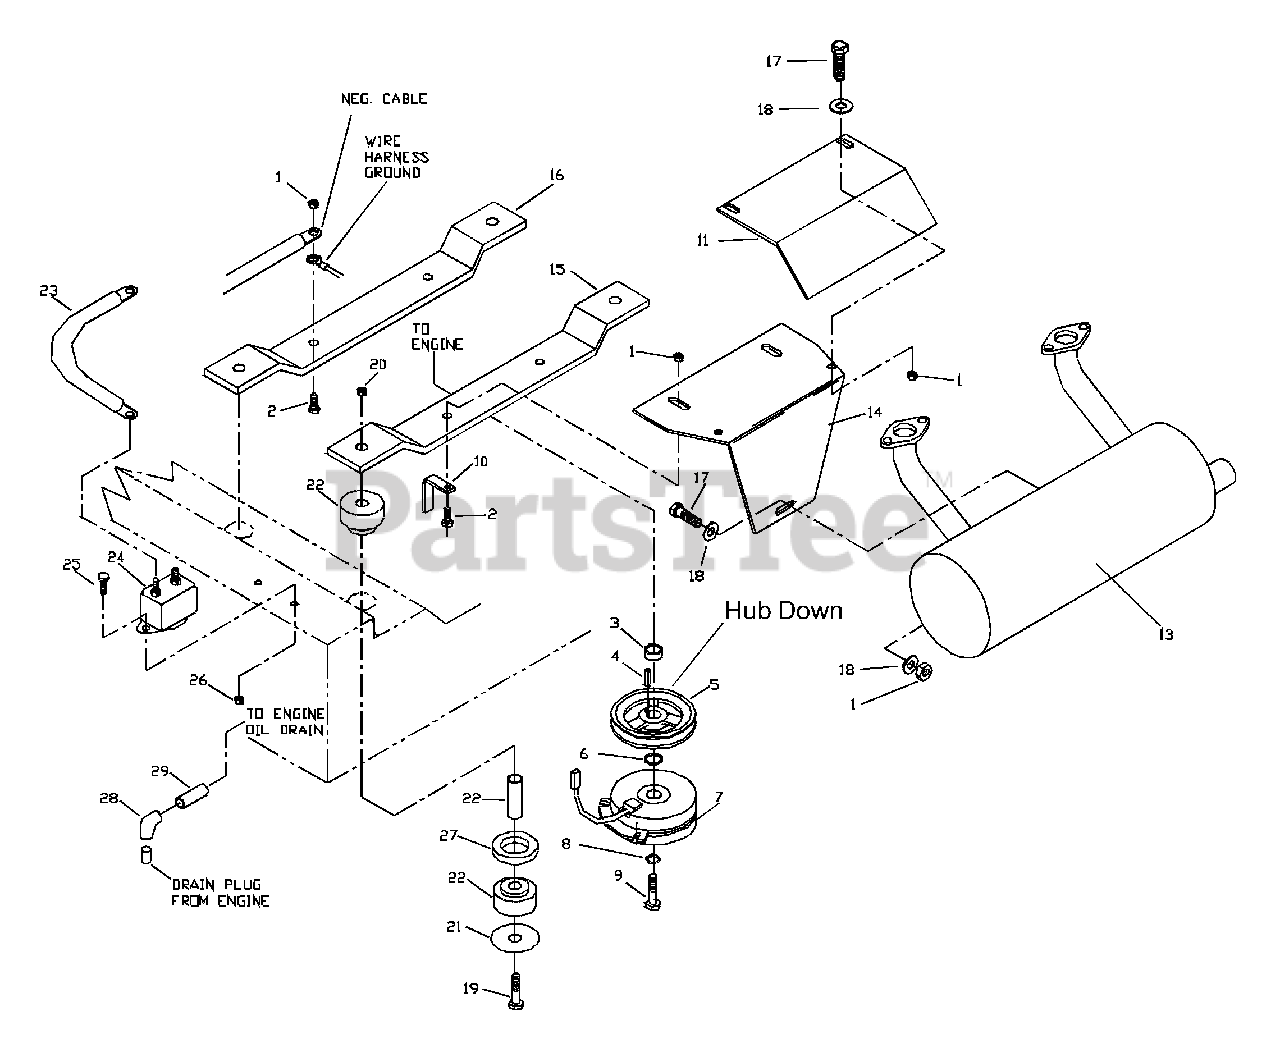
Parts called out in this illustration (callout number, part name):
1	NUT 5/16C CTR. LOCK
2	HCS 5/16C X 1.75
4	KEY 1/4SQ. X 1.0
7	ELECTRIC CLUTCH
8	7/16 LOCKWASHER
9	HCS 7/16F X 2.5
10	CLUTCH TIE DOWN
11	MUFFLER GUARD (KAW.)
12	KOHLER PIGTAIL
12	KAWASAKI PIGTAIL
13	MUFFLER, KOHLER
13	MUFFLER, KAWASAKI
14	MUFFLER BRACKET
15	ENGINE MOUNT
16	ENGINE MOUNT
17	HCS 5/16C X 3/4
18	5/16 FLAT WASHER
19	HCS 1/2C X 3.25
20	NUT 1/2C NYLOC
21	ISOLATOR WASHER
23	CABLE, POSITIVE (KAW)
24	SOLINOID (KAW)
25	HCS 1/4C X 5/8 (KAW)
26	1/4C CTR. LOCK (KAW)
27	ISOLATOR SPACER
28	ELBOW (KOHLER)
29	3/8 NPT X 1.5 PIPE (KOHLER)
32	HCS 5/16 X 2
